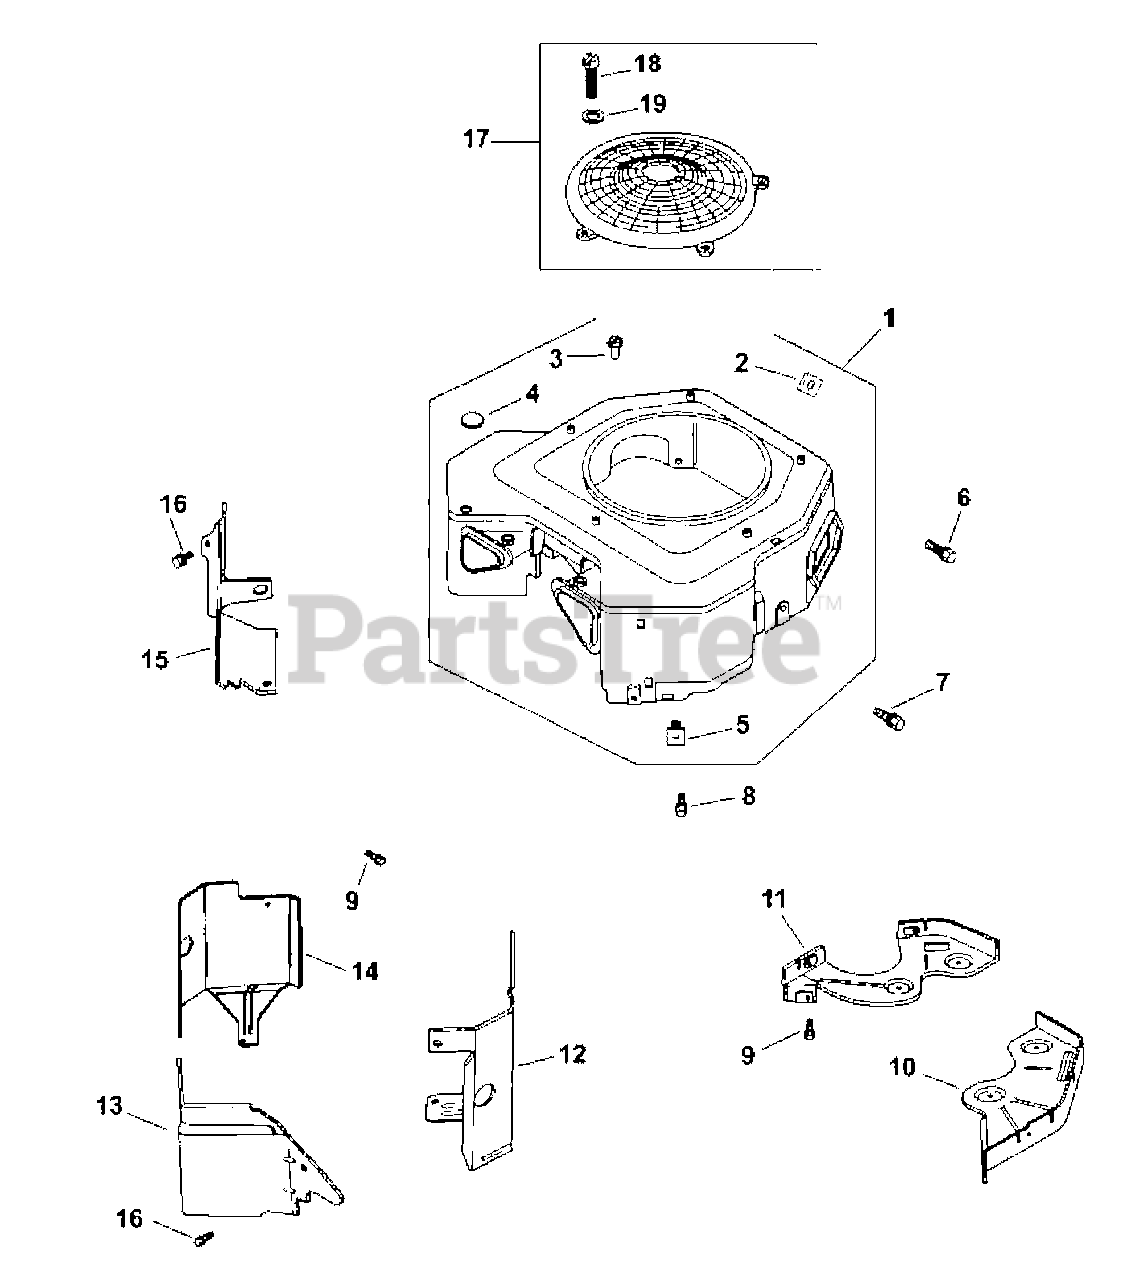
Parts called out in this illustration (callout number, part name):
1	Blower Housing
2	Plastic Nut
4	Button Plug (9/16")
6	Hex Flange Screw (M5 x .8 x 16)
7	Hex Flange Screw (M5 x .8 x 16)
8	Hex Flange Screw (M5 x .8 x 20)
9	Hex Flange Screw (M6 x 1.0 x 16)
10	Backing Plate #2 Side
11	Backing Plate #1 Side
12	Cylinder Barrel Baffle # 2 Side
13	Valley Baffle # 2 Side
14	Cylinder Barrel Baffle # 1 Side
15	Valley Baffle # 1 Side
16	Hex Flange Screw (M5 x .8 x 10)
17	Fixed Guard Kit
19	Pan Head Screw
